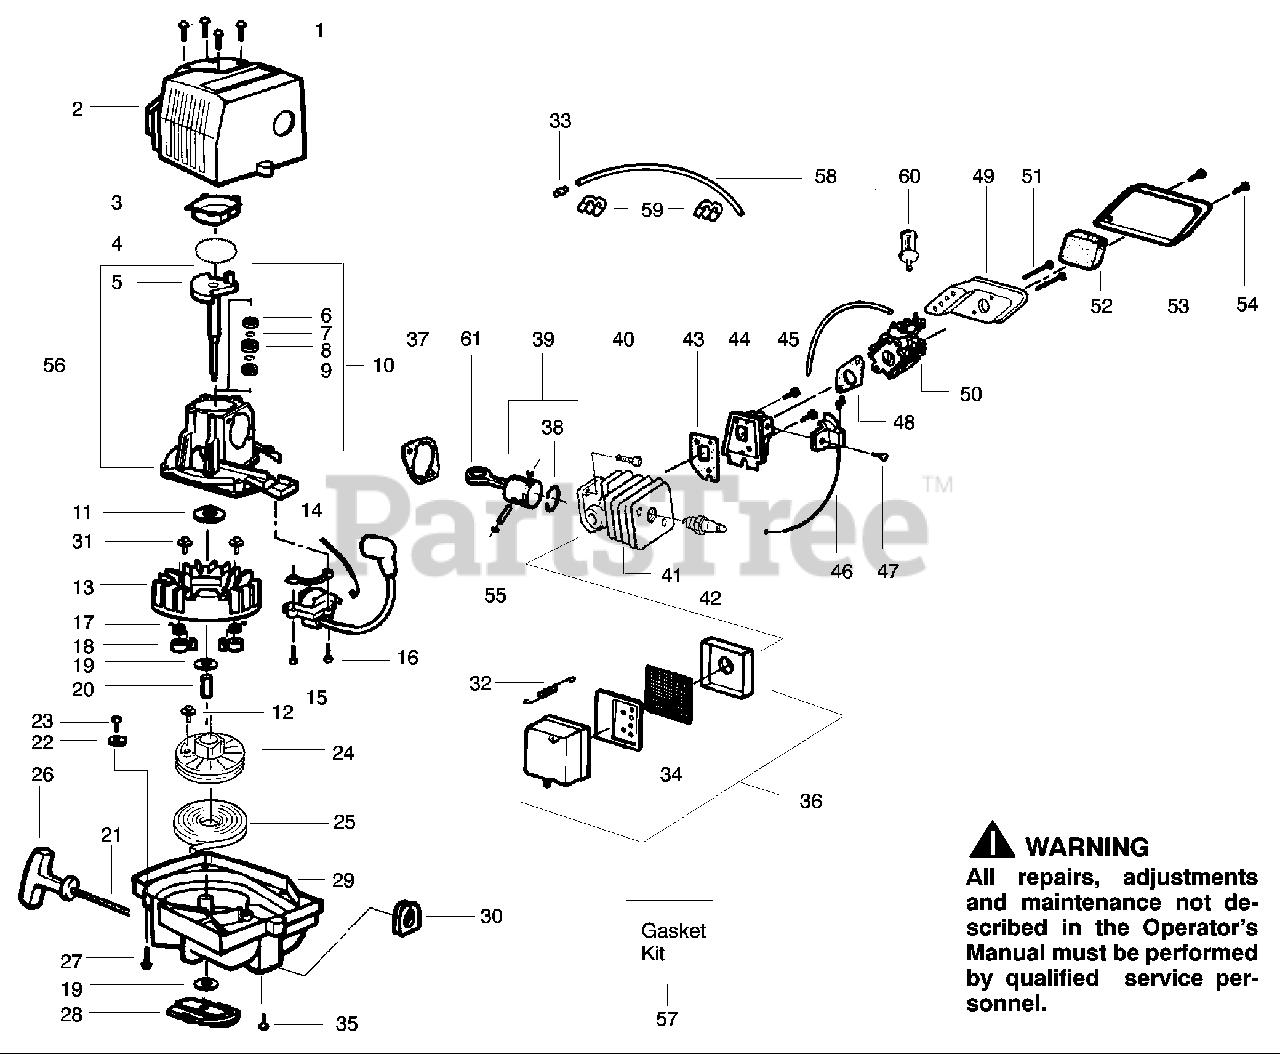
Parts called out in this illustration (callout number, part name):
1	Screw
3	Cover-Crankcase
4	O-ring/Gasket/C'case
5	Assy-Crankshaft
6	Bearing-Inner
7	Retainer-C'case
8	Seal-Crankcase
9	Bearing-Outer
10	Assy-Crankcase
11	Ring-Ret. (C'shaft)
13	Assy-Flywheel
14	Spacer-Ignit. Mod.
15	Module-Ignition
17	Spring-Starter Dog
18	Starter Dog
19	Washer-Flat
20	Spacer-Flywheel
21	Kit-Rope
22	Retainer
24	Kit-Starter Pulley
25	Spring-Starter
26	Handle-Starter
28	Kit-Clutch Ass'y.
29	Assy-Fan Housing
30	Grommet-Ignit. Module
32	Spring-Muffler
33	Fitting-Fuel Line
34	Screen-Muffler
36	Kit-Muffler
37	Gasket-Cylinder
38	Ring-Piston
39	Kit-Piston
41	Kit-Cylinder
42	Spark Plug (RCJ-8Y)
43	Gasket-Cylinder/Carb. Adaptor
44	Carb. Adaptor
46	Assy-Throttle Cable
48	Gasket-Carburetor
50	Kit-Carb. Ass'y.
52	Air Filter- Foam
53	Air Filter -Cover
55	Piston Pin Retainer
56	C'case & C'shaft Assy.
57	Kit-Gasket
58	Kit-Fuel Line
59	Retainer Clip
60	Assy-Fuel Pick-up
61	Kit-Connecting Rod
